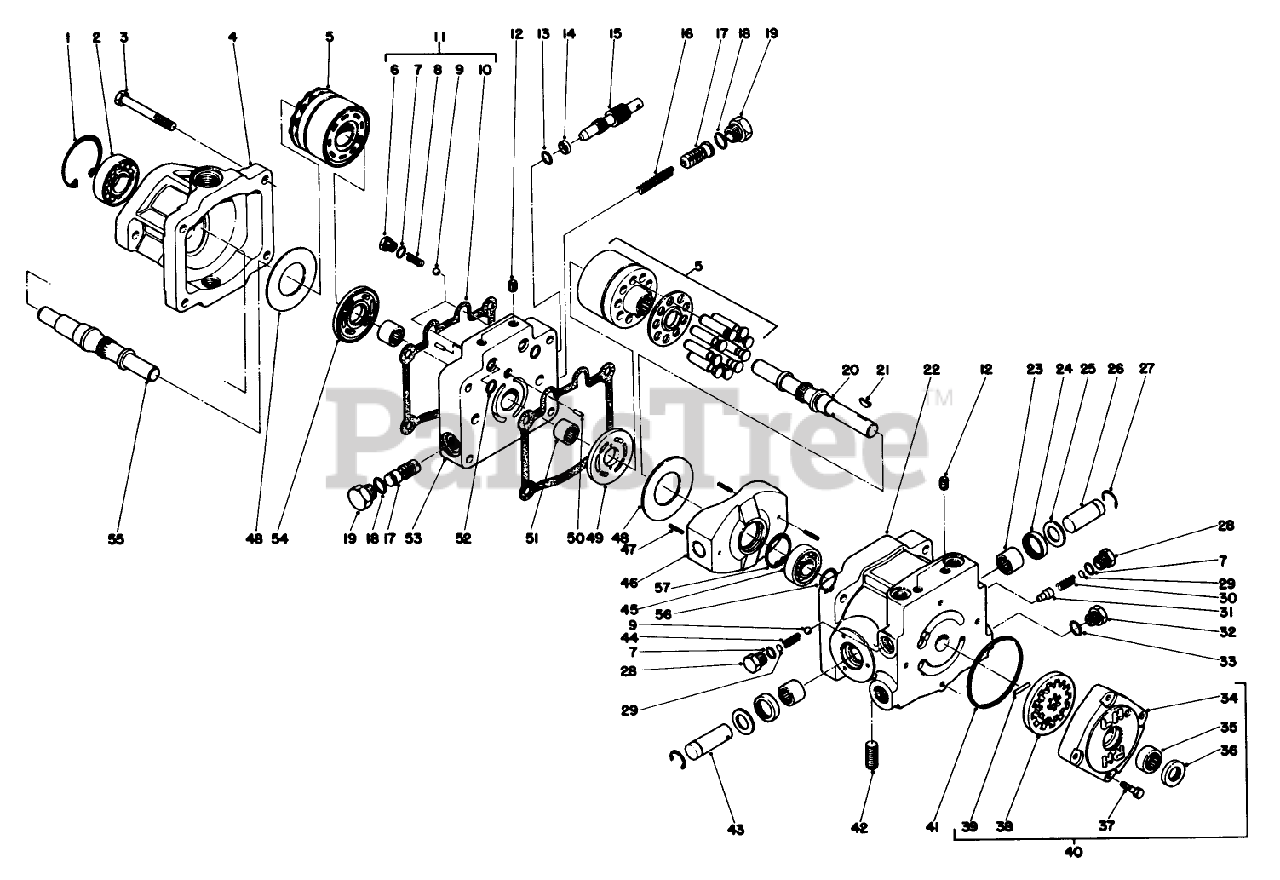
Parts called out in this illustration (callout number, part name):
1	RING-SNAP
2	BEARING
3	SCREW-HH
4	Motor Housing
5	Cylinder Block Kit
6	PLUG-VALVE, CHECK
7	O-RING
8	SPRING-VALVE
10	GASKET
11	Check Valve Kit (Incl. Ref. #6-10)
12	PLUG-PIPE
13	O-RING
14	RING-BACK UP
15	By Pass Valve
16	SPRING-VALVE
17	VALVE ASM
18	O-RING
19	PLUG-HYD, HH
20	PUMP SHAFT
21	KEY-WOODRUFF
22	PUMP HSG
23	BEARING-NEEDLE
24	SEAL-LIP
25	WASHER-FLAT
26	SHAFT-TRUNNION
27	RING-RETAINING
28	PLUG-HH
29	PACK-SHIM
30	SPRING-VALVE
31	Cone-Relief Valve
32	PLUG-HH
33	O-RING
34	HOUSING-PUMP, CHARGE
35	NEEDLE BRG
36	SEAL-OIL
37	SCREW-HH
38	Gerotor ASM
39	PIN-STRAIGHT, HEADLESS
40	Charge Pump (Incl. Ref. #34-39)
41	O-RING
42	UNION-FILTER
43	SHAFT-TRUNNION
44	SPRING-VALVE
45	BEARING-BALL
46	PLATE-SWASH, VARIABLE
47	PIN-SPRING
48	PLATE-THRUST
49	PLATE-VALVE, PUMP
50	PIN-DOWEL
51	BEARING-NEEDLE
52	O-RING
53	Center Section
54	PLATE-VALVE, MOTOR
55	Motor Shaft
56	RING-SNAP, EXT
57	RING-RETAINING
